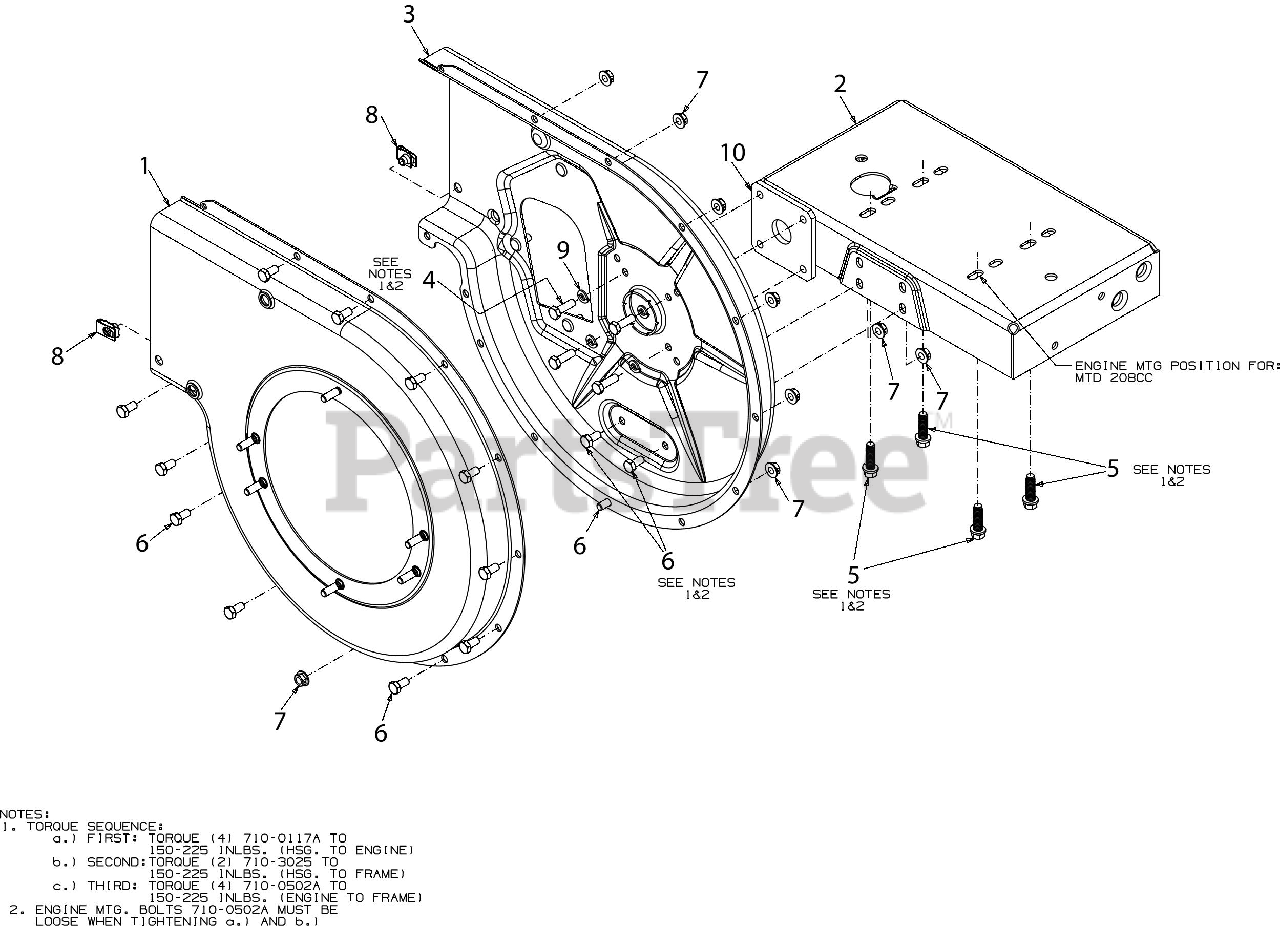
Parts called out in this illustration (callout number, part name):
1	FLAIL HOUSING ASSEMBLY (LH)
2	FRAME ASSEMBLY
4	HEX HEAD CAP SCREW 5/16-24 x 1.00 GR5
5	SCREW 3/8-16 x 1.250
6	SCREW 5/16-18X .625 GR5
7	HEX FLANGE NUT
8	U-NUT
9	LOCK WASHER 5/16
10	ENGINE PLATE
